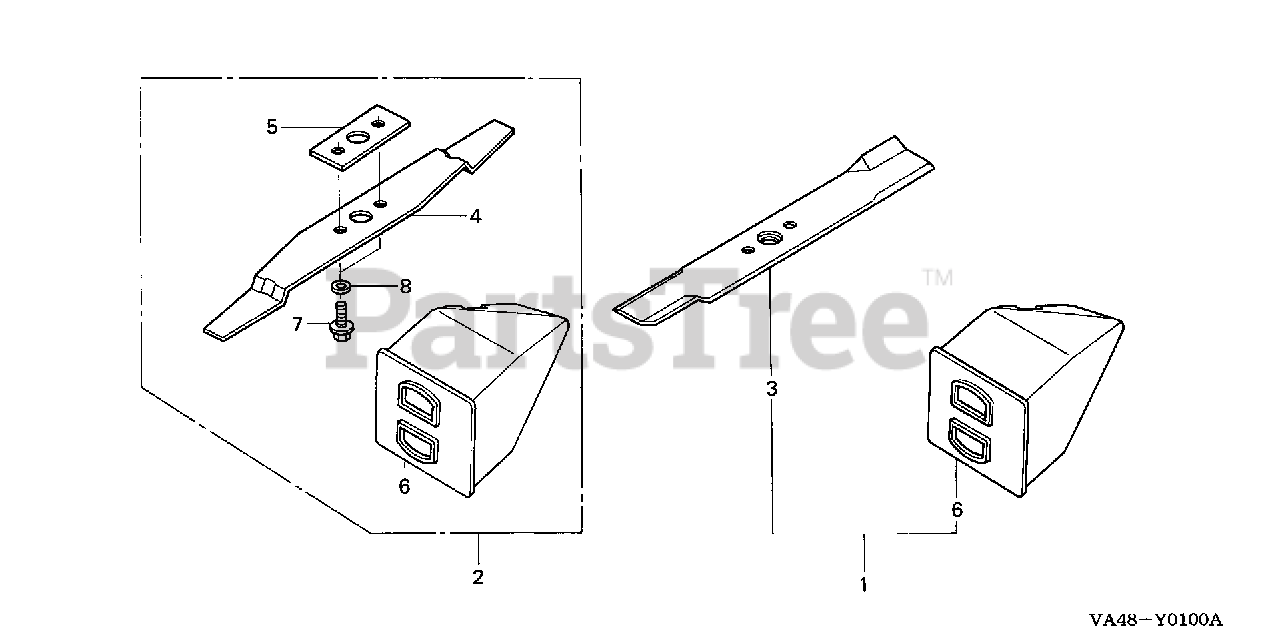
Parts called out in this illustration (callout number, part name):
1	MULCHING KIT
3	BLADE, MULCHING (21")
6	STUFFING
